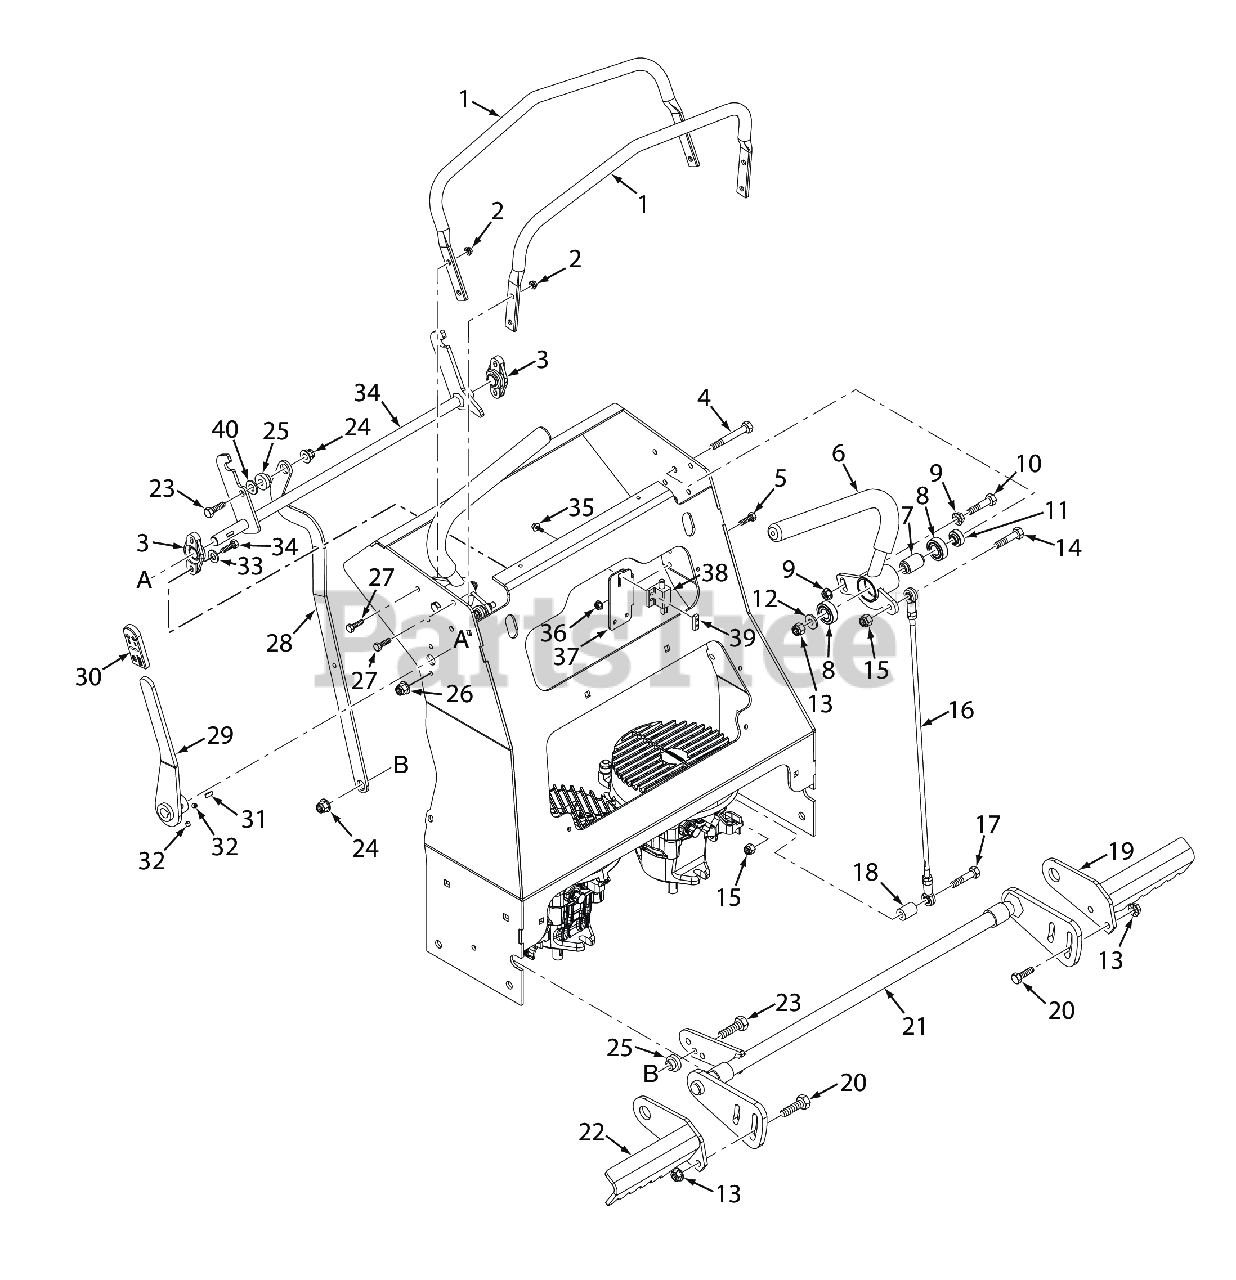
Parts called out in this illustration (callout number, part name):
1	Reference Bar
2	Nut, Serrated Flange 5/16-18 (Right Front Engine Mounting, Briggs and Kohler Only)
3	Bearing
4	Capscrew, Hex Head 3/8-16 x 3.25"
5	BOLT, HEX HEAD, 1/4-20 X 3/4 GR.5
6	Handlebar Assy., LH
6	Handllevar Assy., RH
7	Spacer, Bearing
8	BEARINGS, BALL, NEUTRAL RETURN
9	NUT, 3/8-16 SERRATED FLANGE HEX HEAD
10	Capscrew, Hex Head 3/8-16 x 2.0"
11	Spacer, Controls
12	Flatwasher, 3/8 (.391 x .938 x .105 HD) Grade 8
13	HEX NUT, ELASTIC STOP LOCK, 3/8-16
14	Bolt, 5/16 - 18 x 1 - 1/4" Hex Head
15	HEX NUT, ELASTIC STOP LOCK, 5/16-18
16	Linkage Assy., Steering
17	Hex Head Socket, 5/16-18 x 1" (36)
17	Bolt, Hex Head 5/16-18 x 2-1/2" (x3) (35BV & 37BV-EFI)
18	Spacer (excludes SVRII-36A)
19	Brake Paddle Weldment, RH (36)
19	Brake Paddle Weldment, RH
20	Carriage Bolt, 3/8-16 x 1.0"
21	Bellcrank Weldment, Brake (36)
21	Bellcrank Weldment, Brake
22	Brake Paddle Weldment, LH
23	Bolt, Hex Head 3/8-16 x 1-1/4", Kawasaki FX / FS
24	Nut, Flange Elastic Stop Nut, 3/8-16
25	BUSHING, BRONZE - .376 ID X .627 OD
26	Nut, Flanged Elastic Stop 1/4-20
27	BOLT, SERRATED FLANGE HEX HEAD 5/16-18 X 3/4"
28	Link, Brank Engage (36)
28	Link, Brake Engage
29	Brake Lever Assy. - SVRII (Incl. #30)
30	Grip, Parking Brake
31	KEY, WOODRUFF #61, 3/16 X 5/8
32	Set Screw 1/4-20 x 1/4"
33	Flatwasher, 1/4 (.281 x .625 x .065)
34	Lock Weldment, Neutral
35	Screw, Hex-Slotted Washer Head #10 32 x 3/4"
36	NUT, 1/4-20 SERRATED FLANGE HEX HEAD
37	Bracket, Neutral Switch
38	Switch, Interlock (see below)
38	Switch, Interlock, Park Brake Normally Open
39	Plate, Threaded
40	Flatwasher, 3/8" Special (.391 x .938 x .105)
